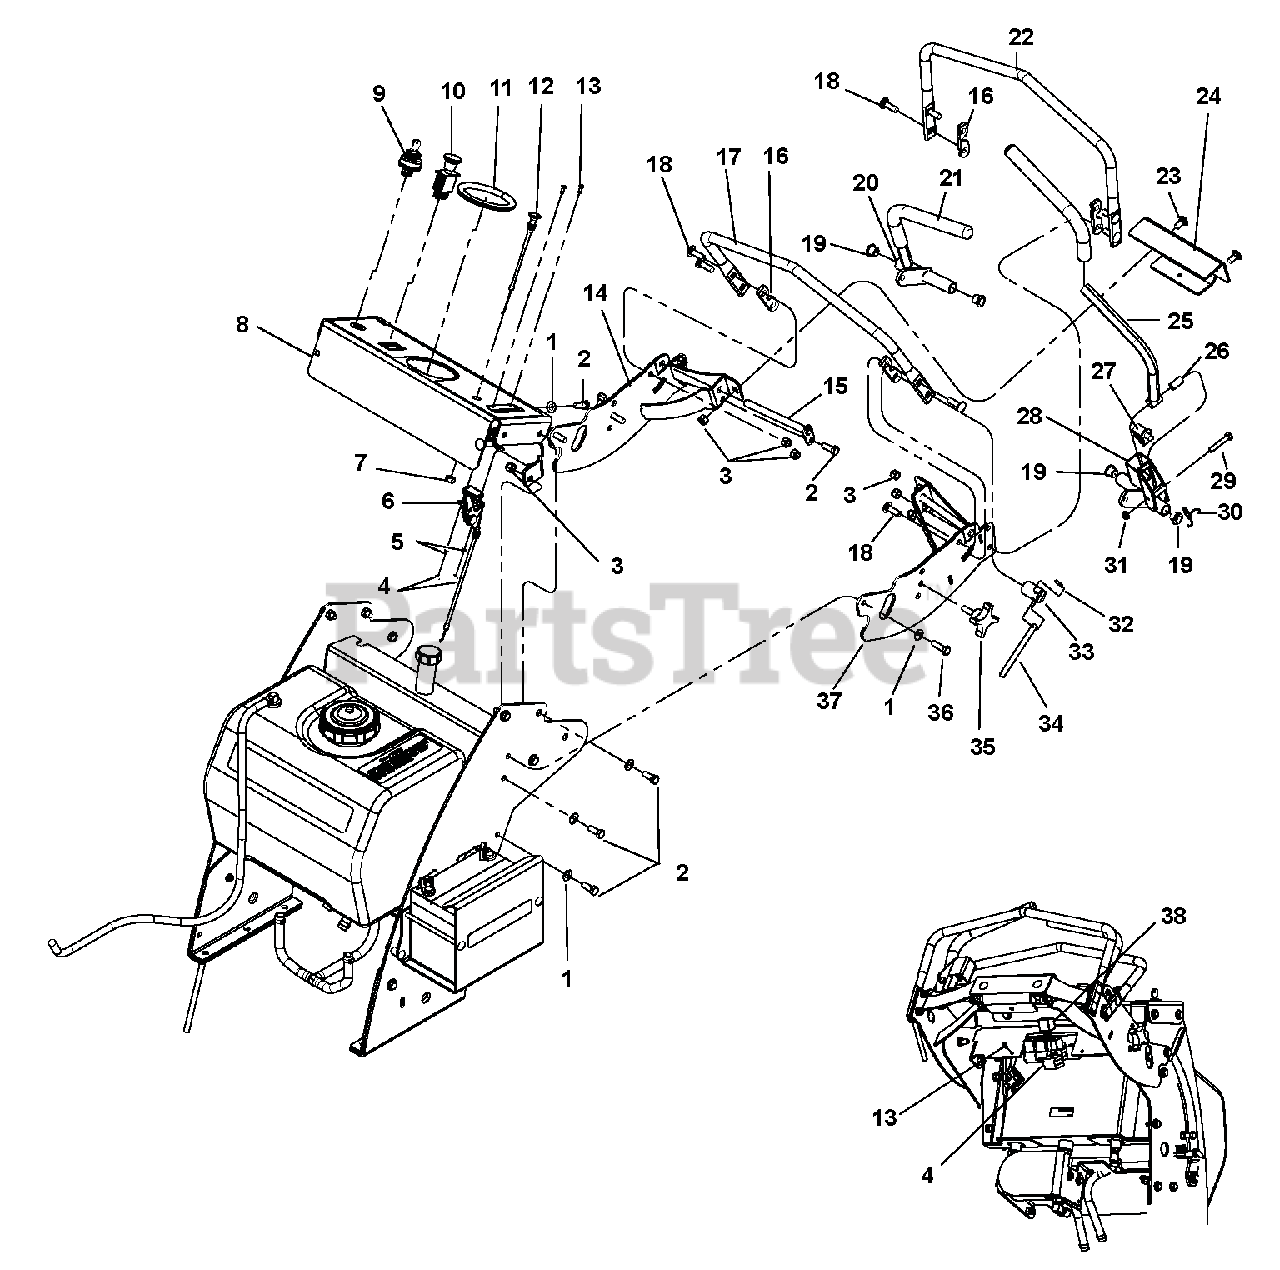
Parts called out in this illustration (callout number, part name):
1	WASHER, .406X.813X.065 FLAT Y
2	BLT-HEX .38-16X1.00 GR5 YWZC
3	LOCKNUT, 3/8-16 NYLOC Y
4	NUT-KEPS 8-32
5	WASHER, #8 MED SPRG LOCK Y
6	CABLE, THROTLE 49.5"
7	NUT, 3/8-24 STD HEX Y
8	ASSY, CONSOLE W/DECAL NG
9	SWITCH, KEY - 3 POSITION
10	SWITCH, PTO ENGAGEMENT
11	TRIM, RUBBER EDGE 12"
12	CABLE, CHOKE 48.0"
13	SCREW,8-32X1/2
14	WLDT, RH HANDLE MOUNT 5 DEG
15	WLDT, PIN AND LOCK Y
16	SHIM, 5 DEG SPEED BAR
17	SUPPORT, HANDLE PAINTED
18	BLT-RDHDSQNK .38-16X1.25 G5YZ
19	BRG, FLG .500X.625X.500 BRNZ
20	WLDT, RH DRIVE LEVER 5 DEG
21	GRIP, CONTROL
22	SUPPORT, HANDLE PAINTED
23	BLT-RDHDSQNK .38-16X.75 G5YZ
24	PLATE, HANDLE MOUNT LINK
25	WLDT, LH DRIVE LEVER 5 DEG
26	SPACER, .500 X .330 X .980
27	SWITCH, SEAT OVERIDE (N.O.)
28	WLDT, LH HANDLE MOUNT 5 DEG
29	BLT-HEX .31-18X1.75 GR5 YWZC
30	SPRING, TOR 1.00X.062 Y
31	LOCKNUT, 5/16-18 NYLOC Y
32	PIN, SPRING
33	BASE, LOCK LEVER Y
34	LEVER, LOCK Y
35	KNOB, 3/8 X 1.25 - 4 PRONG
36	BLT-HEX .38-16X1.25 GR5 YWZC
37	WLDT, LH HANDLE MOUNT 5 DEG
38	RELAY, ISO MINI ELEC.
39	HARNESS, WIRE NON ELEC PB WALK
40	HARNESS, MY2011FSWLK ELE START
